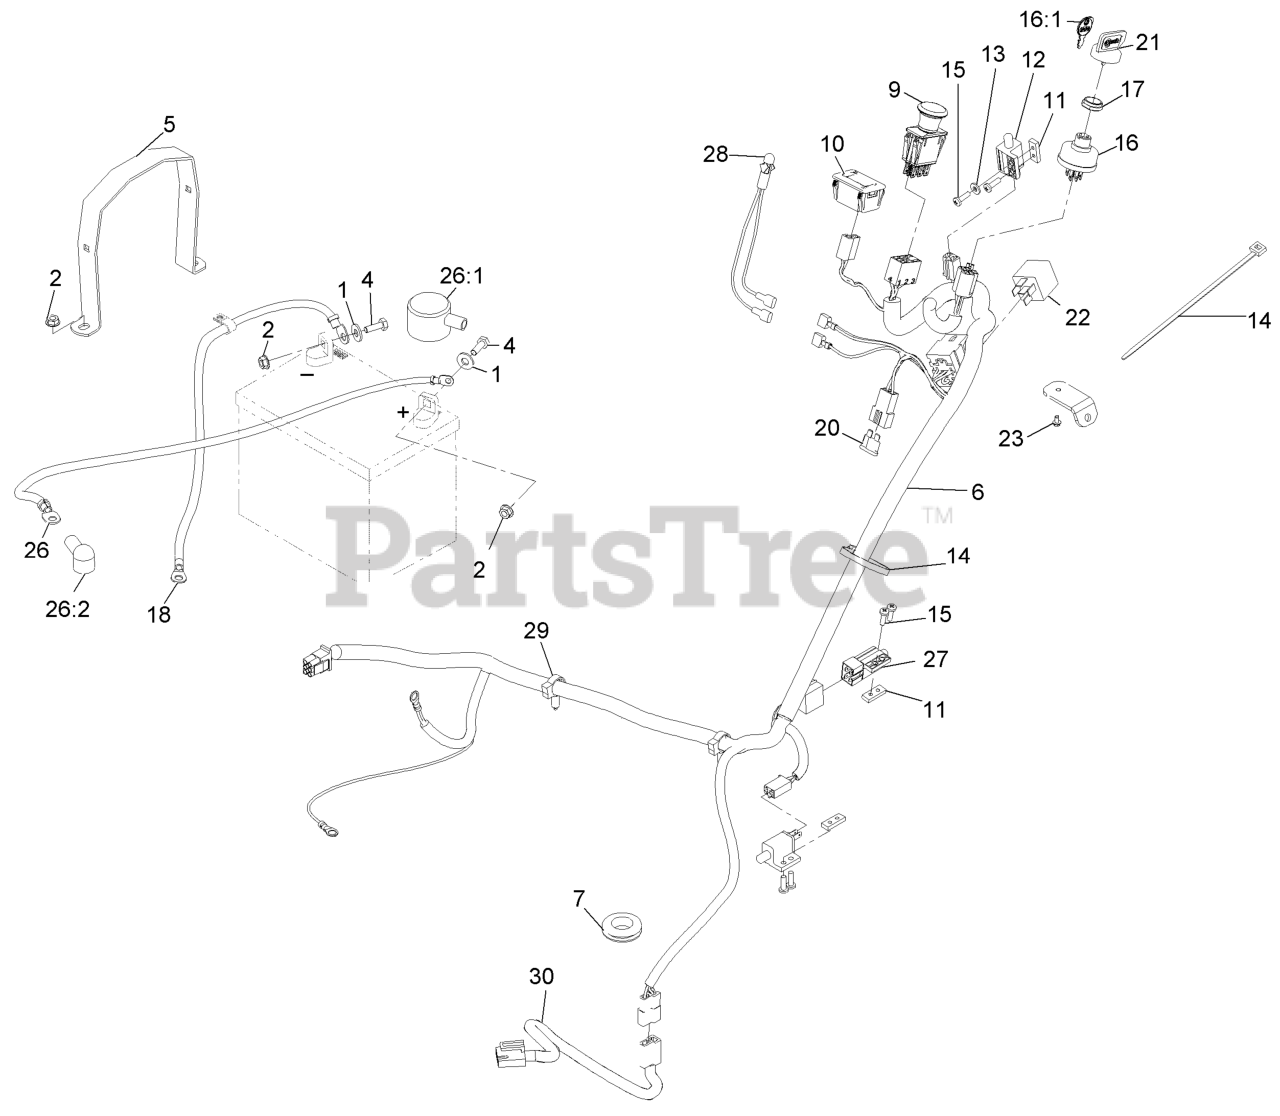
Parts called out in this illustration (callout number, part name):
1	WASHER-FLAT
4	SCREW-HH
5	STRAP,BATTERY HOLDDOWN
6	HARNESS-WIRE
7	GROMMET
9	SWITCH-PTO
10	HOURMETER
11	PLATE-TAPPED
12	SWITCH-OPEN, NORMALLY
13	WASHER-FLAT
14	TIE-PLASTIC
15	SCREW-PPH
16:1	KEYS-IGNITION (SPARE PAIR
17	NUT-SWITCH, IGNITION
18	WIRE-GROUND
20	FUSE-BLADE TYPE, 20 AMP
21	KEY-IGNITION
23	SCREW-HWH
26	POSITIVE BATTERY CABLE AS
26:1	INSULATOR-BATTERY
26:2	INSULATOR-SOLENOID
27	SWITCH-BRAKE
28	INDICATOR-LED, RED
29	Clip-Harness
30	HARNESS-CLUTCH PIGTAIL
